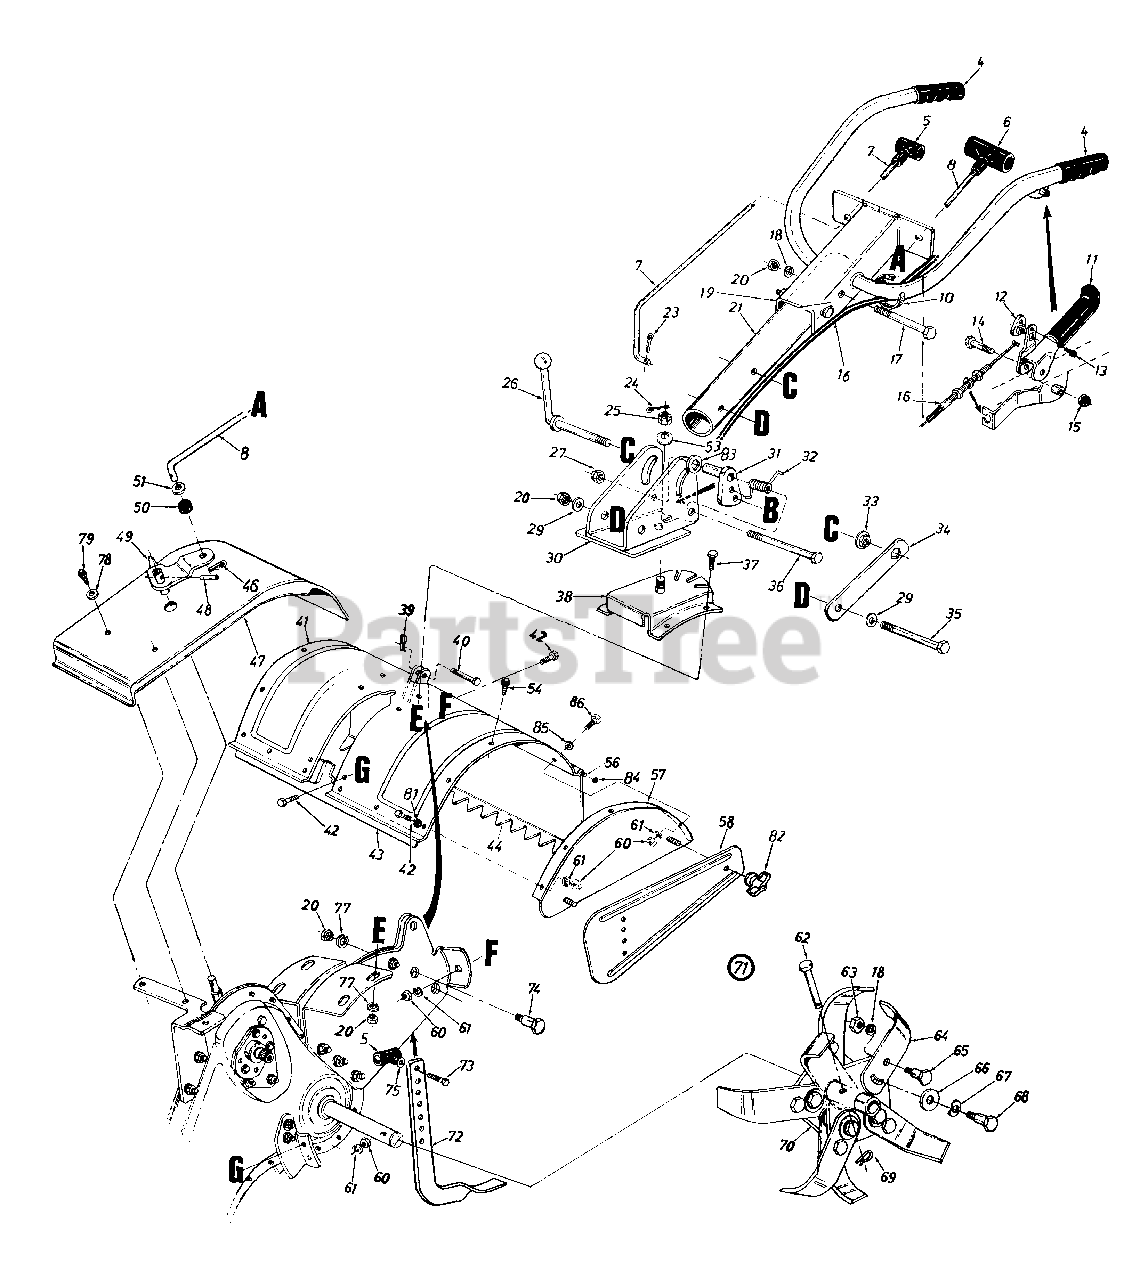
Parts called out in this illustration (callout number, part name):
4	Handle Grip
5	Small "T" Knob
6	Large "T" Knob
7	Clutch Rod
8	Control Rod 37" Lg.
10	Cable Tie-Self Clinching
12	Barrel Cable Hold Down
13	Hex B-Tap Scr. #10 x .44" Lg.
14	Hex Bolt 3/8-24 x 2.25" Lg.
15	Hex Jam L-Nut 3/8-24 Thd.
16	Clutch Control Cable 46" Lg.
17	Hex Bolt 3/8-16 x 3.00" Lg.
18	L-Wash. 3/8" I.D.-H.D.
24	Cotter Pin 3/32" Dia. x 1.25" Lg.
25	Hex Slotted Nut 5/8-18 Thd.
26	Handle Adj. Crank
27	Hex Cent. L-Nut 3/8-16 Thd.
29	Bell-Wash. .4" I.D. x .87" O.D.
32	Spring Handle Adj. (Torsion)
33	Hex Flange Nut 3/8-24 Thd.
34	Bracket Hex Nut Retainer
35	Hex Bolt 3/8-16 x 3.25" Lg.
36	Hex Bolt 3/8-16 x 3.00" Lg.-Gr. 8
37	Hex Bolt 3/8-16 x .1" Lg.
40	Clevis Pin .375" Dia.
43	Bracket Reinforcement-18"
46	Intern. Cotter Pin 5/16" Dia.
49	Shifting Crank Ass'y.
50	Rubber Washer .33" I.D.
51	Fl-Wash. .4" I.D. x 1.25" O.D.
53	Bell-Wash. .63" I.D. x 1.25"
54	Hex Wash. Tap Scr.
56	Tiller Flap Rod
61	L-Wash. 5/16" I.D.
62	Clevis Pin .375" Dia.
63	Hex Nut 3/8-24 Thd.
65	Shld. Bolt 1/2" Dia. x .175
66	Fl-Wash. .51" I.D. x 1.50"
67	Bell-Wash. .515" I.D. x 1.14"
68	Shld. Bolt 1/2" Dia. x .320
69	Intern. Cotter Pin
73	Hex Bolt 3/8-16 x 1" Lg.
74	Shld. Bolt 1/2" I.D. x .62" Lg.
75	Fl-Wash. 3/8" I.D. x 5/8" O.D.
77	L-Wash. 3/8" I.D.
78	Fl-Wash. .281" I.D. x .62"
79	Hex Wash. Self-Tap Scr. 1/4-20 x .50" Lg.
82	Plastic Knob 5/16-18 Thd.
83	Fl-Wash. .406" I.D. x .875" O.D.
84	End Cap
85	Flat Washer .33 x .630 x .06
86	Shoulder Screw
